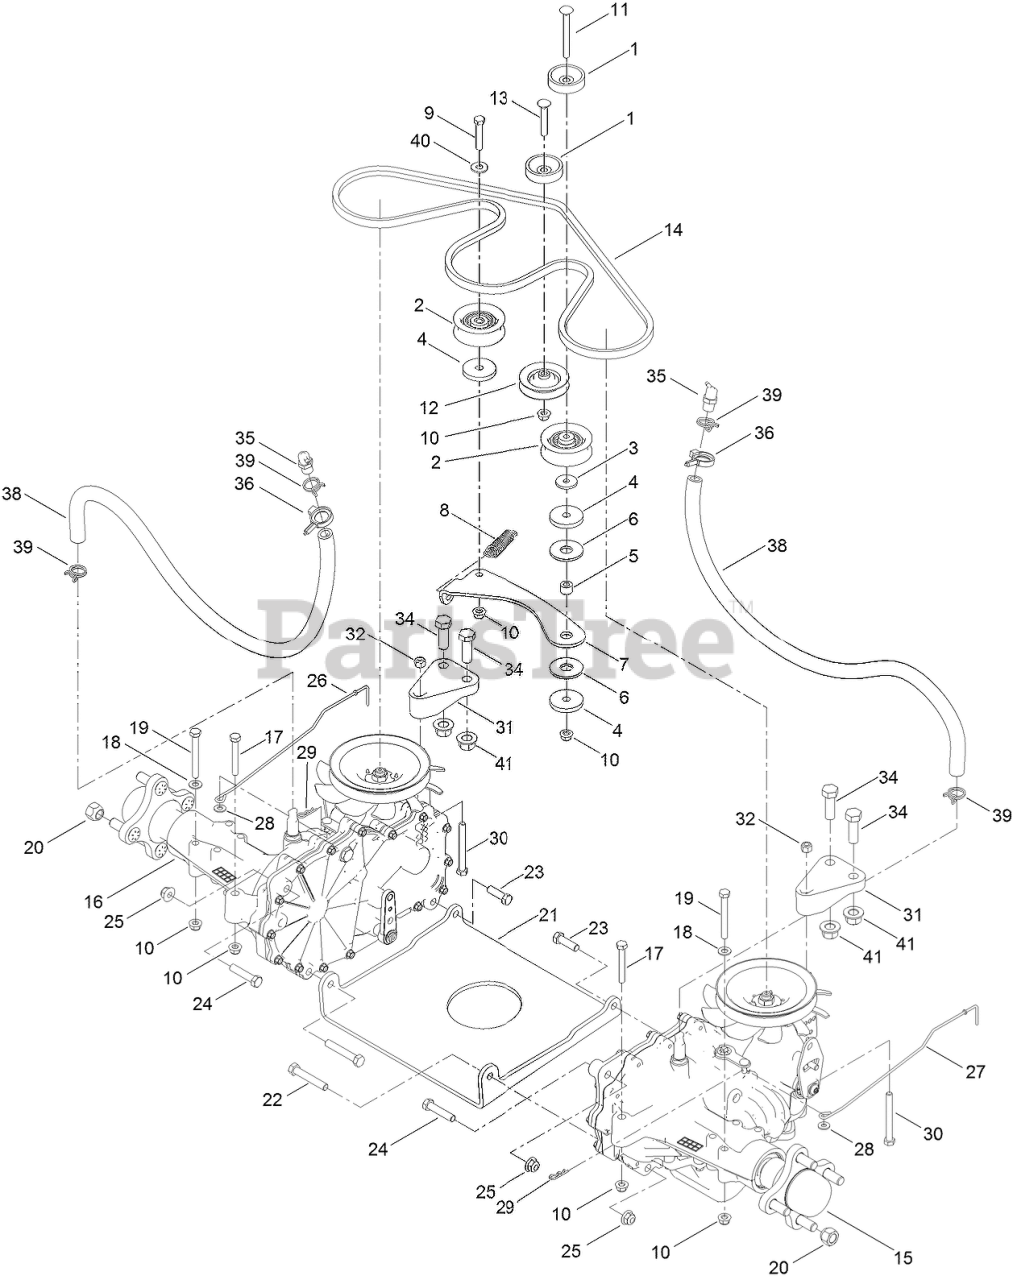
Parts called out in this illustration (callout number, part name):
1	SPACER
2	PULLEY-IDLER, FLAT
3	WASHER
4	WASHER-PLAIN
5	BUSHING
6	WASHER-FRICTION, COMPOSITE
7	ARM-IDLER
8	SPRING-PEDAL, RETURN
9	SCREW-HH
10	NUT-HF, NI
11	SCREW-CARR
12	PULLEY-IDLER
13	BOLT-CARR
14	V-BELT
15	LH HYDRO TRANSMISSION ASM
16	RH HYDRO TRANSMISSION ASM
17	SCREW-HH
18	WASHER-PLAIN
19	SCREW-HH
20	NUT-LUG
21	PLATE-CROSS, HYDRO
22	SCREW-HH
23	SCREW-HH
24	SCREW-HH
25	NUT-HF, NI
26	ROD BYPASS, RH
27	ROD BYPASS, LH
28	WASHER-FLAT
30	SCREW-HH
31	SUPPORT-HYDRO, REAR
32	NUT-LOCK, NI
34	SCREW-HH
35	BREATHER KIT
36	CLAMP-HOSE
38	HOSE-HYDRO
39	CLAMP-HOSE
40	WASHER-FLAT
41	NUT-LOCK
